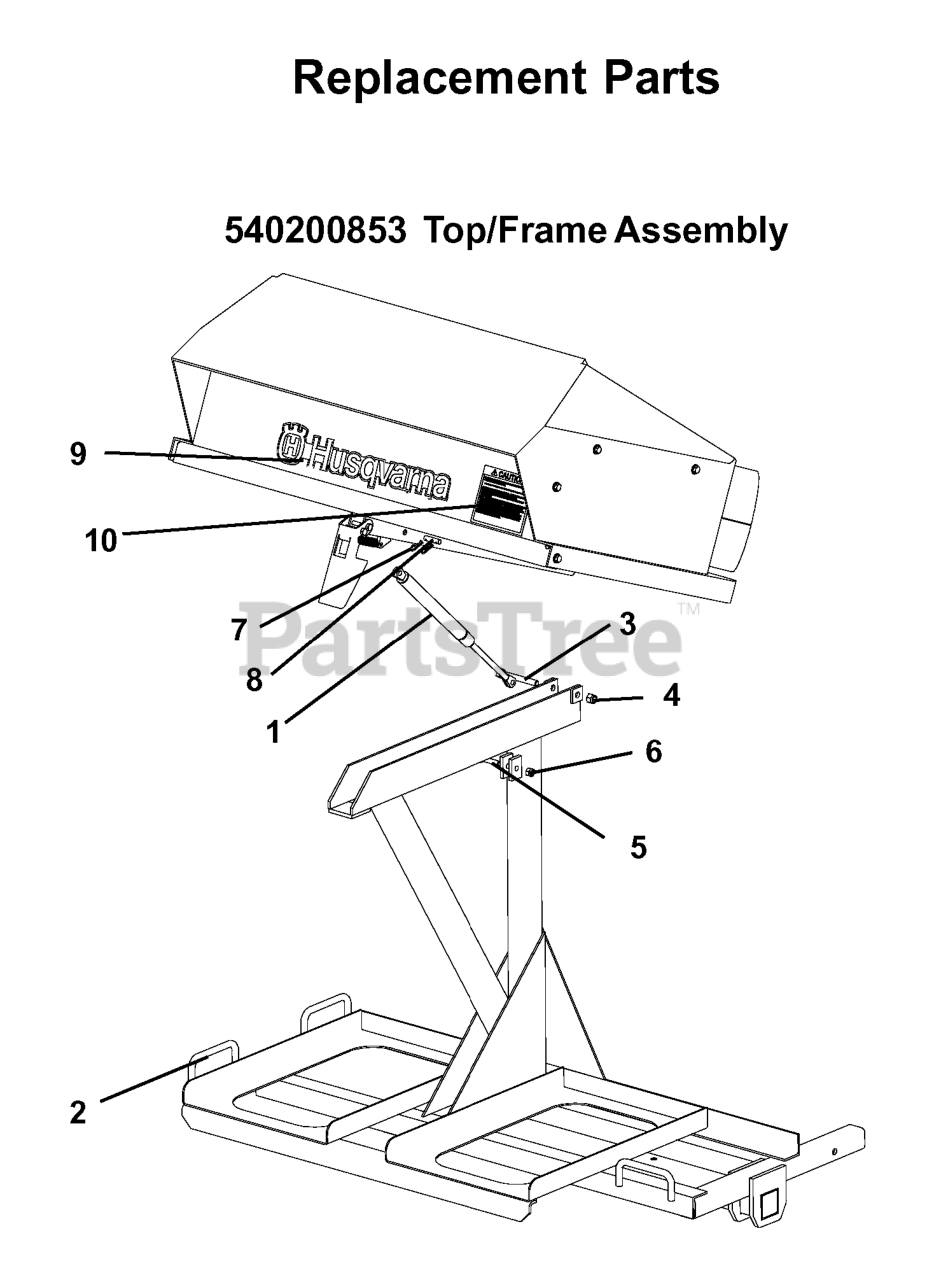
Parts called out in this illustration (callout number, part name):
1	GAS SPRING - CZ9
2	FRAME, BLACK
3	Bolt, Hex, 3/8"-16 x 3"
4	NUT 3/8 NYLOC
5	Bolt, Hex, 5/16"-18 x 1-1/2"
6	HEX NUT - NYLON LOCK 5/16-18
7	PIN, HAIR COTTER #13 5/64 X 1
8	Pin, Clevis, 5/16" x 1-1/4" w/ 2 holes
9	R/B 104804 DECAL HUSQ 2.94X15
10	DECAL, CAUTION LIST
